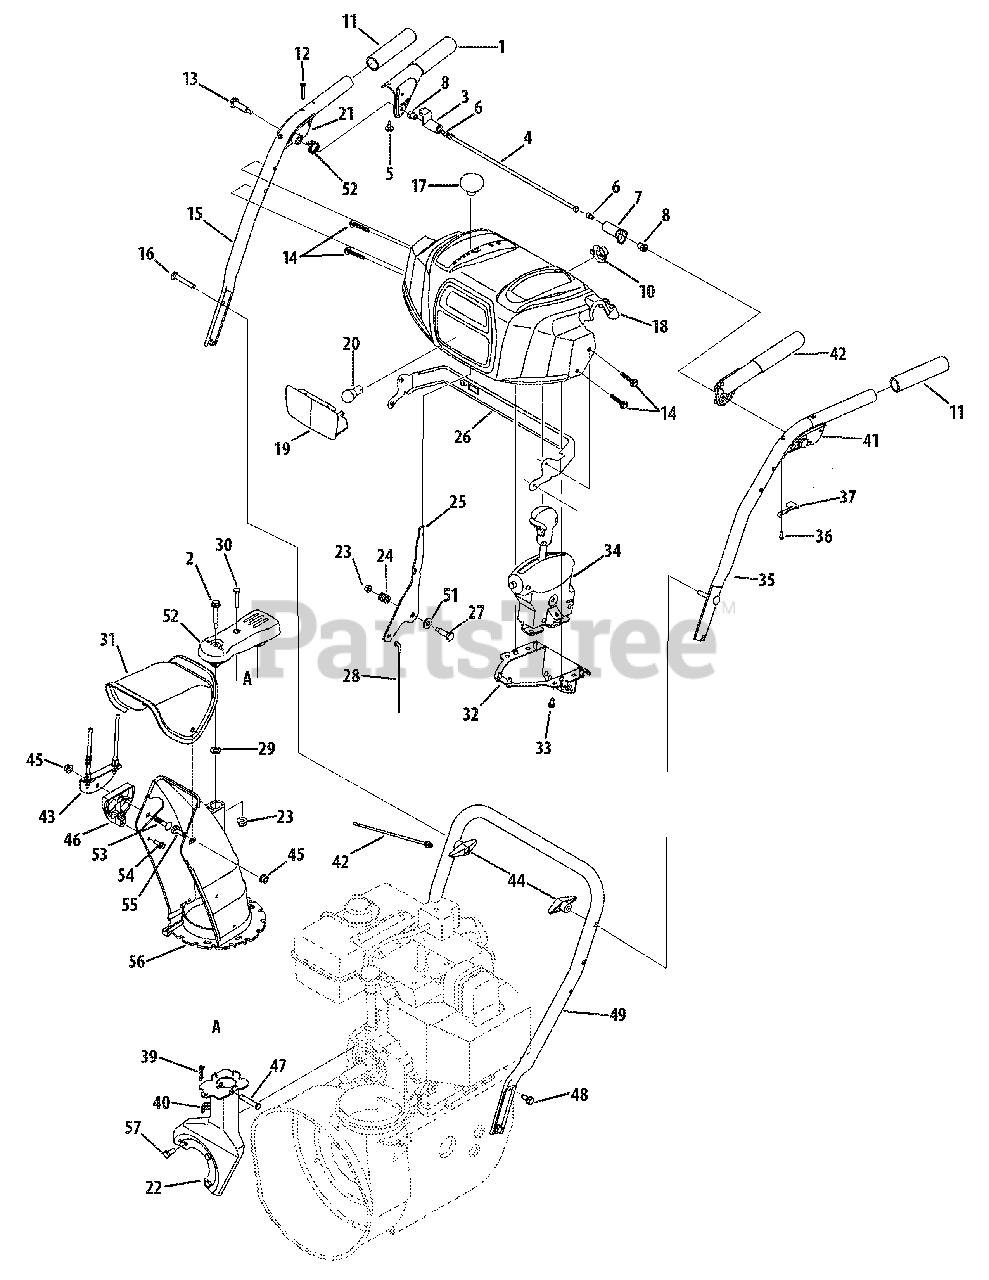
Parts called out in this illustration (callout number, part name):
1	Handle Engagement Assembly RH
2	Flange Shoulder Screw
3	Lock plate
5	Rubber Bumper
6	Screw, 1/4-20 x .375
7	Clutch Lock Cam
8	Shoulder Nut, 1/4-20
10	Light Socket
11	Handle Grip
12	Screw, #10-24 x 0.375
13	Shoulder Screw 1/4-20 x 1.345
14	Screw, 1/4-20 x 1.625
16	Carriage Screw, 5/16-18 x 2.25
17	Shift Knob
18	Handle Panel
20	Lamp
21	Handle Clutch Lock RH Assy
24	Compression Spring
27	Shoulder Screw
28	Speed Selector Cable
29	Flat Washer, .25 x .630 x .0515
30	Hex Screw, 1/4-20 x 1.50
31	Upper Chute
33	Hi-Lo Screw, 1/4-15 x 0.5
34	4-Way Chute Control Assembly
36	Screw, #8-16 x 0.50
37	Clutch Lock Spring
38	Wing Nut, 1/4-20
39	Bow Tie Cotter Pin
40	Cable Tie
41	Handle Clutch Lock LH Assy
42	Handle Engagement Assembly LH
44	Wing Knob
45	Flange Lock Nut, 5/16-18
46	Chute Tilt Cable Guide
48	Screw, 5/16-18 x 0.75
50	Torsion Spring
51	Flat Washer
52	Joystick Pulley Cover
53	Carriage Bolt, 5/16-18 x 1.50
54	Hi-Lo Screw, 1/4-15 x .75
55	Carriage Bolt, 5/16-18 x1.0
56	Lower Chute
57	Hex Screw, 5/16-24 x .750
